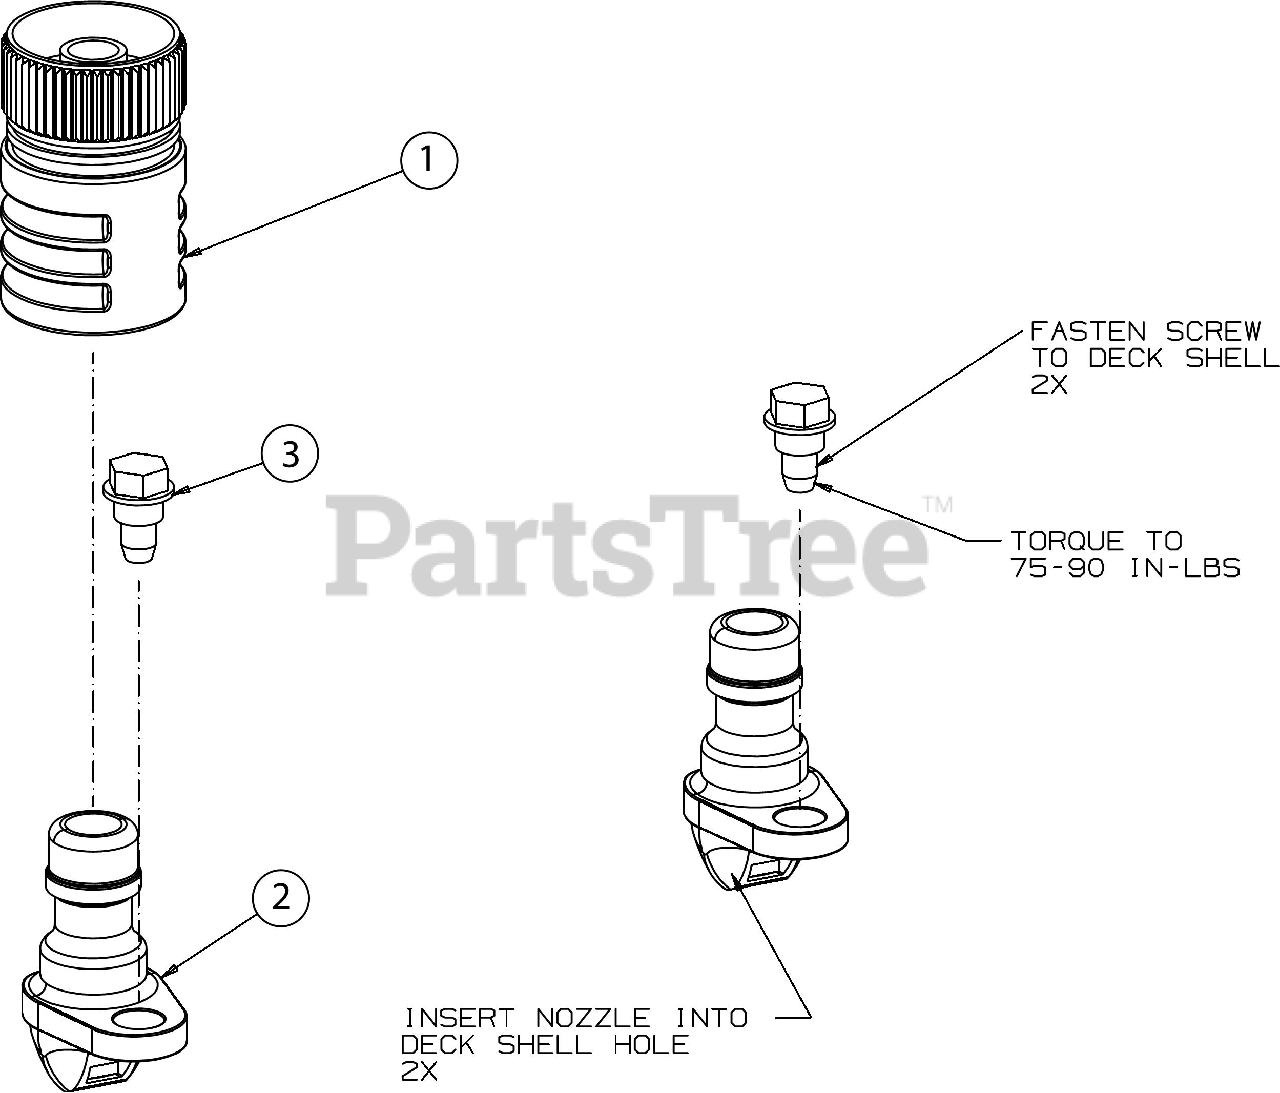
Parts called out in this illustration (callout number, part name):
1	WATER NOZZLE
2	DECK WASH NOZZLE
3	SHOULDER SCREW 1/4-20 X .50
